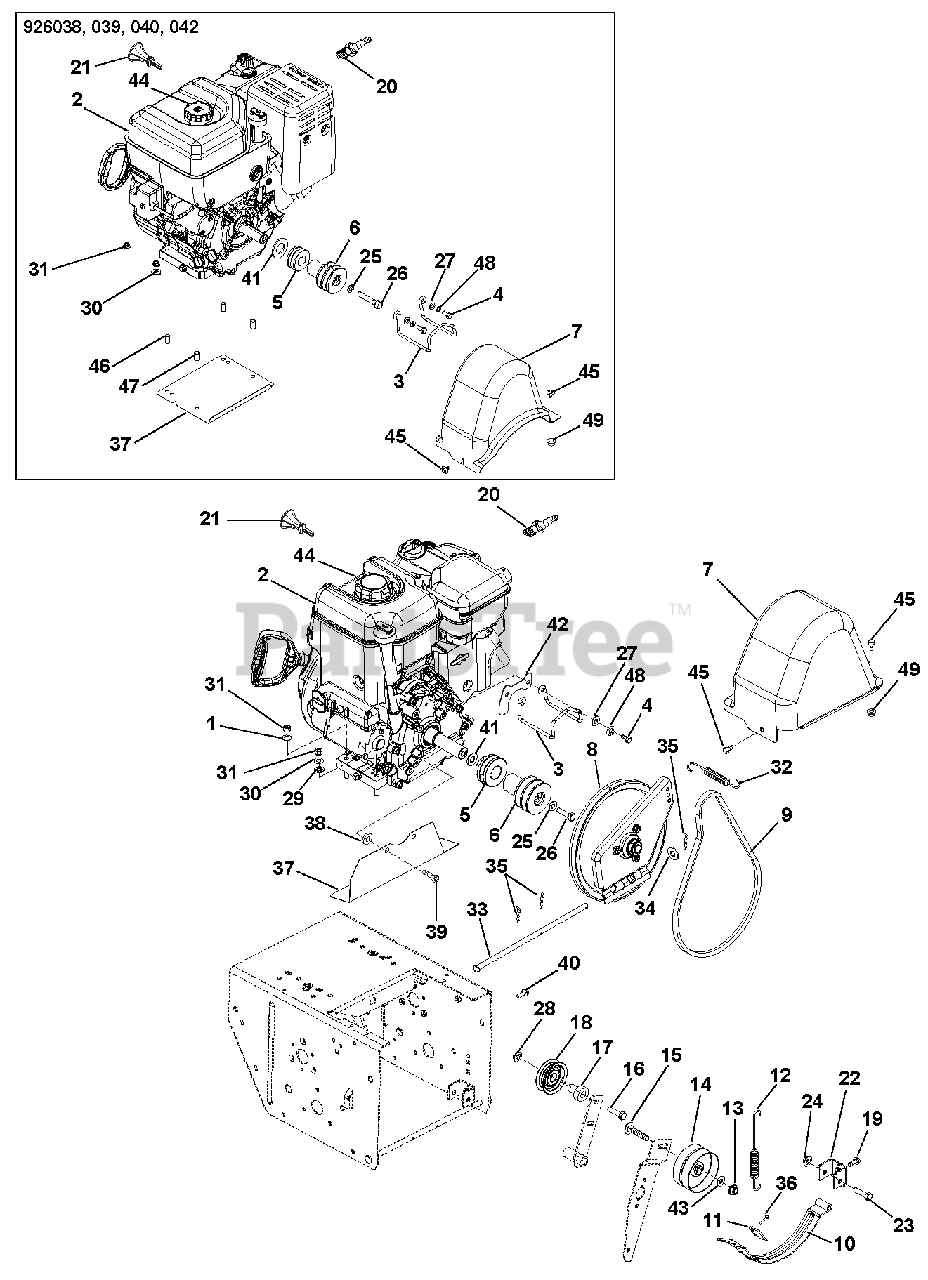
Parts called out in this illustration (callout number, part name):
1	WSHR-LK .312X.097 HVY YWZC
2	ENGINE, BRIGGS PF 1650, 12V
2	ENGINE, BRIGGS PF 2100, 120V
3	FINGER, BELT
4	BLT-HEX .31-24X.75 YWZC GR5
5	SHEAVE, DRIVE
5	SHEAVE, DRIVE 420 BRIGGS
6	SHEAVE, ATTACHMENT 2-GRV
7	COVER, BELT
7	COVER, BELT-LARGE PRO
8	PLATE, SWING ASSEMBLY-DEEP
9	V-BELT, 3L-WRAPPED
10	ARM, BRAKE-ATTACHMENT
11	PAD, BRAKE
12	SG-TENS .056X.60X4.40
13	@NUT-LK-CTR-JAM .375-16 YWZC
14	IDLER, FLAT-2.75 OD X .375 ID
15	@BLT-RHDSSQNK .38-16X1.75 G5YZ
16	@BLT-HEX .31-18X1.25 GR5 YWZC
17	SPCR, BRG .315X.50X.688X.281
18	IDLER
19	SCR-TAP .25-20X.50 HWH TR YWZ
20	PLUG, SPARK 20HP B&S VANGUARD
20	PLUG, SPARK
21	KEY, PUSH/PULL BRIGGS
21	KEY, IGNITION ROTARY B&S
22	PIVOT, BRAKE
23	@BLT-HEX .31-18X2.00 GR5 YWZC
24	@NUT-LK-TOP-FLG .31-18 YWZC
25	@WSHR-LK .38X.094 REG YWZC
25	@WSHR-LK .44X.109 REG YWZC
26	BLT-HEX .38-24X2.25 YWZC GR5
26	BLT-HEX .44-20X2.50 GR5 YWZC
27	@WSHR-FL-STL.344X.688X.065YWZC
28	@NUT-LK-TOP-FLG .31-18 YWZC
29	WSHR-LOCK INT .31 YWZC
30	@WSHR-FL-STL.344X.688X.065YWZC
30	@WSHR-FL-STL.38X.875X.083 YWZC
31	@NUT-LK-CTR .31-18 YWZC
31	@NUT-HEX .31-18 YWZC
31	@NUT-LK-TOP-FLG .31-18 YWZC
32	SG-TENS .048X.50X2.8
33	PIN, PIVOT
34	@WSHR-FL-STL.406X.812X.065 YWZ
35	PIN-HAIR, ENDRIES #25 YWZC
36	RVT-POP .187 YZ
37	BAFFLE, ENGINE
37	BAFFLE,ENGINE-PRO SERIES
38	WSHR-FL-STL .536X1.07X.109 YZ
39	SCR-MCH.31-24X.75FLCTRSK EP80
40	@SCR-TAP .25-20X1.50 HWH TR YZ
41	WSHR-FL-STL- 1.062X2.0X.134 YZ
42	GUARD, BELT COVER - BRIGGS
43	@WSHR-FL-STL.38X.875X.083 YWZC
44	CAP, FUEL - BRIGGS & STRATTON
45	SCR-TAP .25-20X.50 LGHWH TR YZ
46	BSHG-SLV .325X.400X.795
47	BSHG-SLV .328X.50X.75
48	WSHR-LK .312X.097 HVY YWZC
49	NUT-PUSH .25X.50 O.D.
